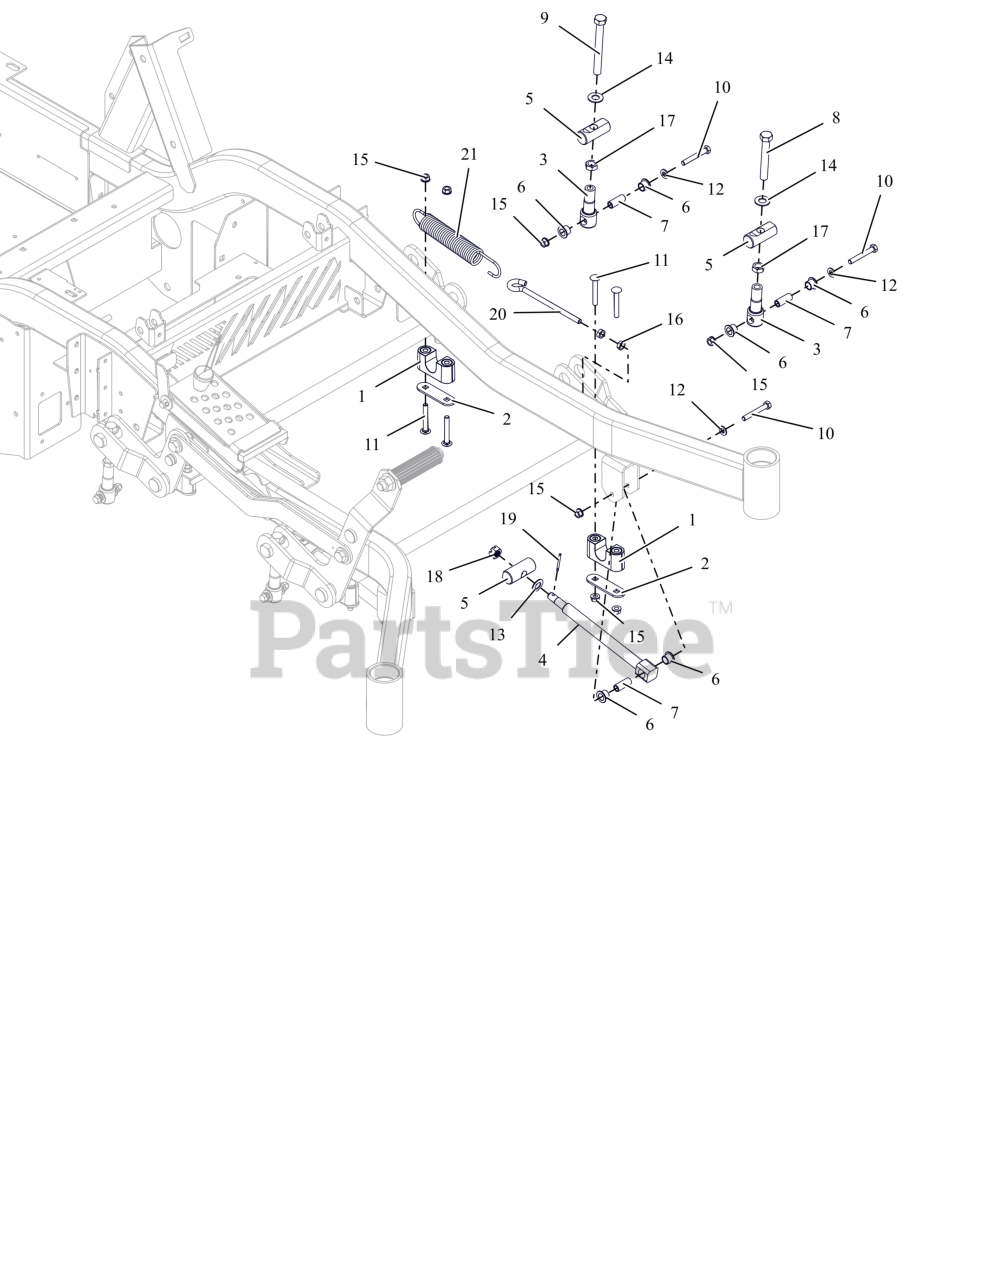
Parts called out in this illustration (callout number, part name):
1	ASM-BUSHING, DECK LIFT
2	PLATE, BEARING SUPPORT
3	LINK, DECK LIFT FORMED
4	DRAG,LINK-HD
5	PIN, DECK LIFT
6	BSHG, FLANGED .50X.625X.50X.062
7	SPCR, .31X.50X1.265
8	BLT, HEX .50-13X3.50F G5 ZCC
9	BLT, HEX .50-13X4.50F G8 ZCC
10	BLT, HEX .31-18X2.25 G5 ZCC
11	BLT, RHSSN.31-18X2.25 G5 ZCC
12	WSHR,FLT .344X.688X.065 ZCC
13	WSHR, BLVL .531 X 1.000 X .062 MZ
14	WSHR, FLT .557X1.040X.102 ZCC
15	NUT,LK-CTR-FLG .31-18 GF ZCC
16	NUT-JAM .375-16 G2 ZCC
17	NUT-JAM .500-13 G2 ZCC
18	NUT-SL .50-13
19	PIN,CTR.12X1.25EXTPRSQCT ZC120
20	BOLT,.38-16 X 5.25-.62 DIA EYE
21	SG-TENS .162X1.25X8.25 WLD 25
